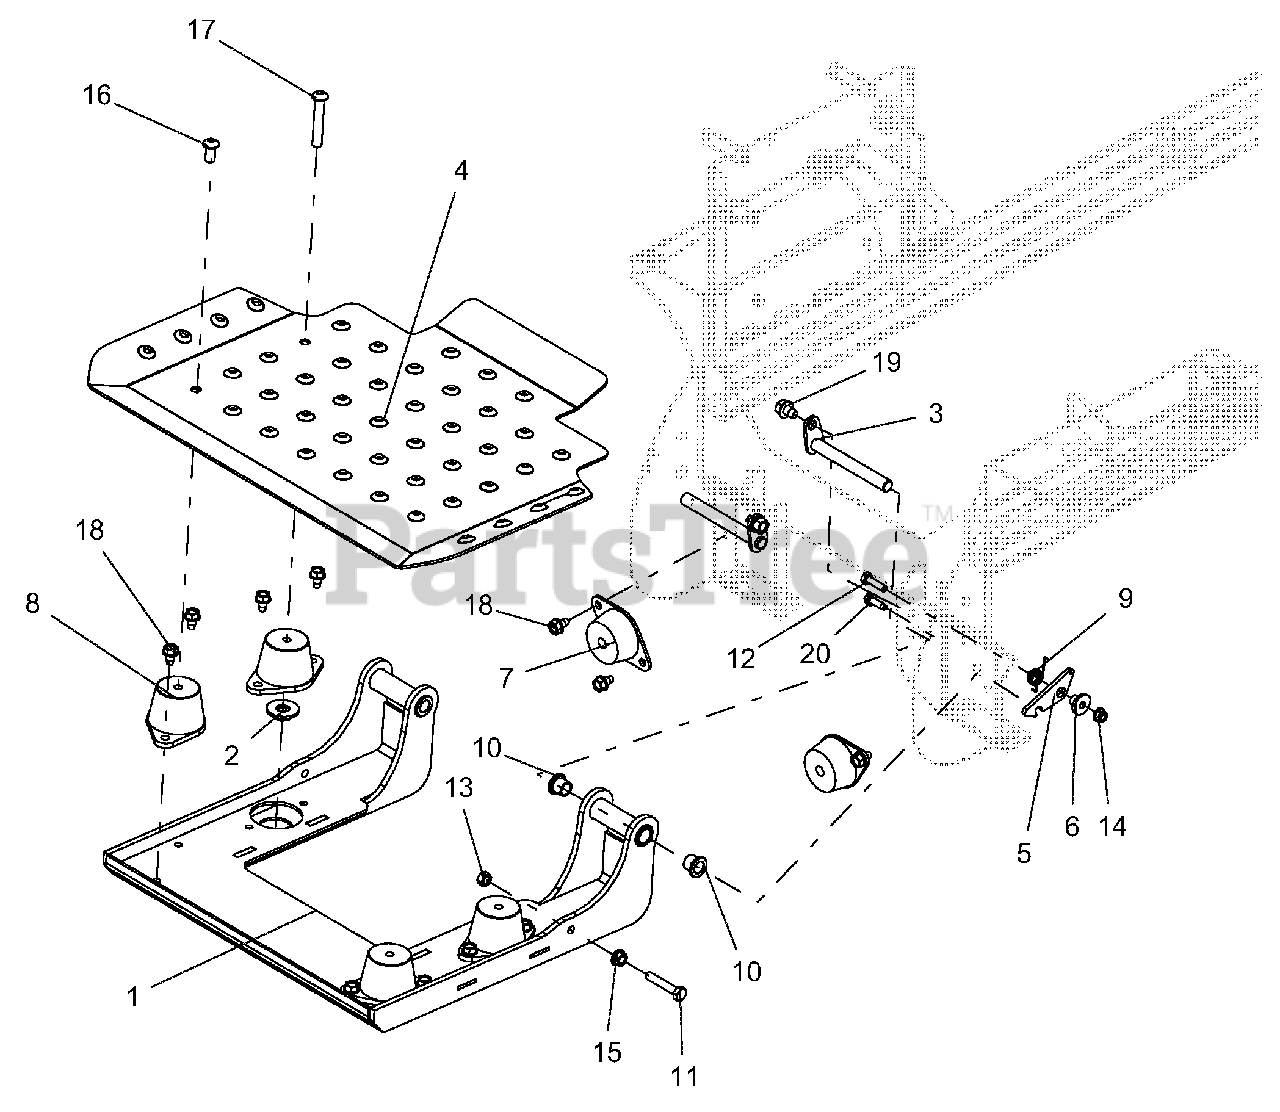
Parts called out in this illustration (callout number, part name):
1	WLDMT, PLATFORM CARRIER
2	WLDMT, SEAT RETAINER
3	WLDMT, PIN
4	PLATE, OPERATOR PLATFORM-RED
5	LATCH, PLATFORM
6	BSHG, FLANGE .26 X .42 X .88 X .33
7	MOUNT, ENGINE. VIBRATION ISO
8	MOUNT, ISOLATOR
9	SPRG, TORSION
10	BRG, FLG .500 X .620 X .500 BRNZ
11	BLT-HEX .31-18X1.75 GR5 YWZC
12	BLT-HEX .25-20X1.00 GR5 YWZC
13	NUT-LK-CTR .31-18 YWZC
14	NUT-LK-NYL-FLG .25-20 YWZC
15	@NUT-SPNLK-FLG .312-18 YWZC
16	SCR-BTHD-SOCKET .38-16X.75 YWZC
17	SCR-BTHD-SOCKET .38-16X2.25 FTH YWZC
18	SCR-TAP .31-18X.50 HWH TR YWZ
19	SCR-TAP .38-16X.50 HWH TR YWZ
20	SCR-TAP .25-20X.75 HWH TR YWZ
